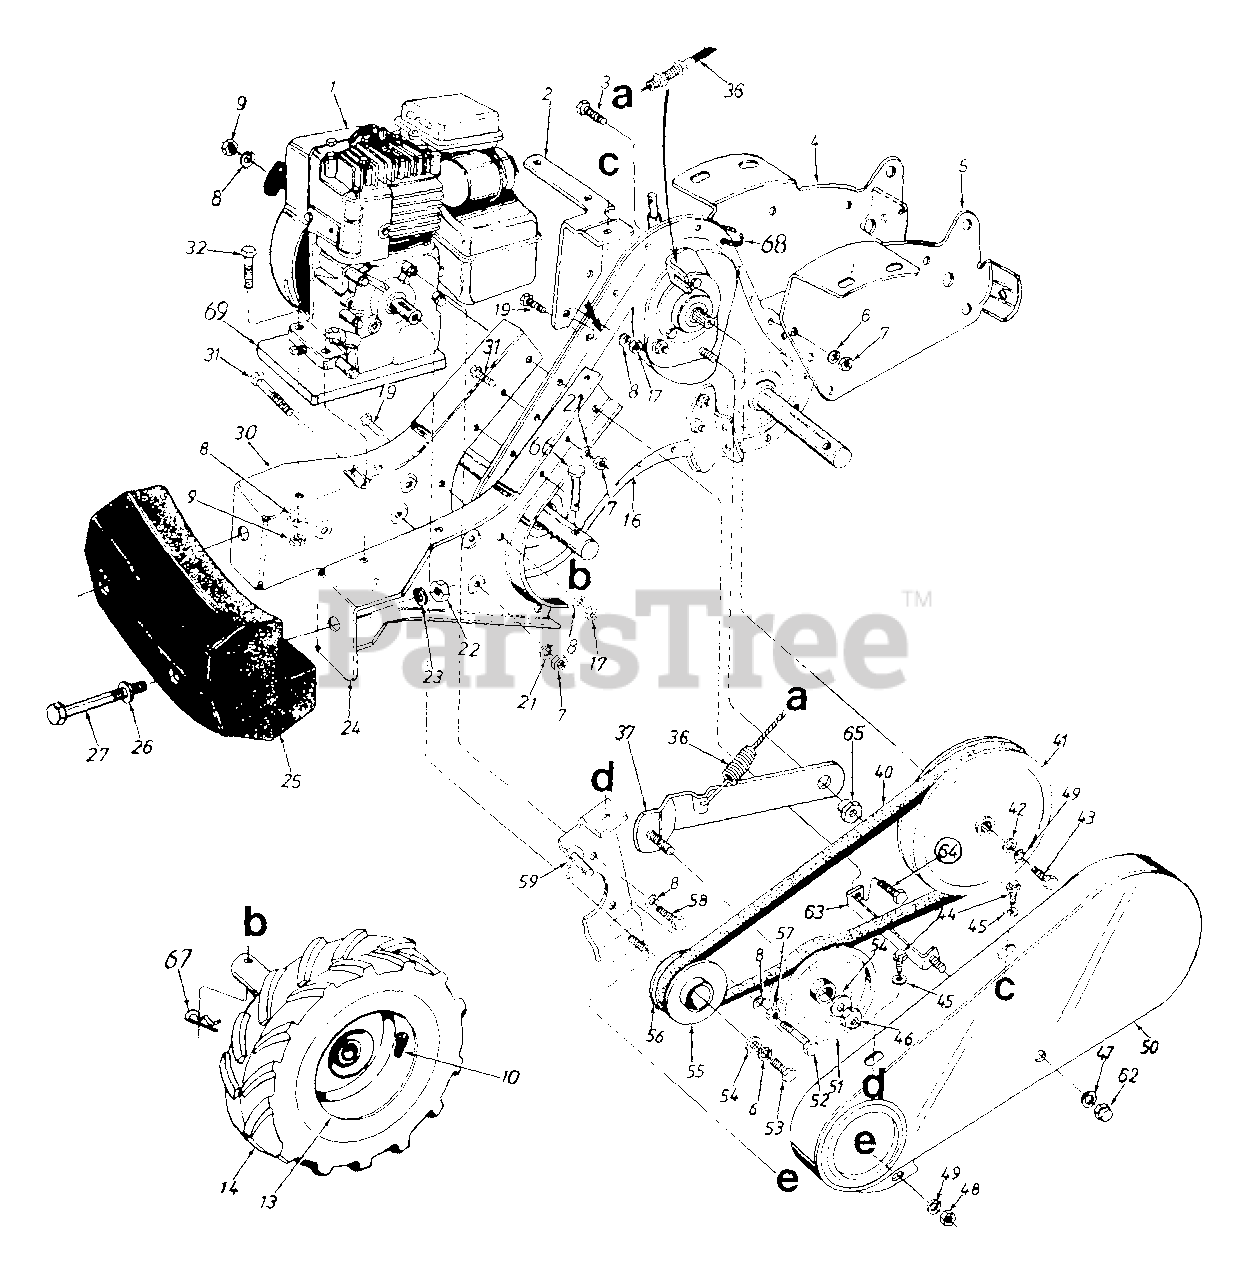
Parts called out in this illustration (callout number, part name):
1	Engine
7	Hex Nut 3/8-16 Thd.
8	L-Wash. 5/16" I.D.
9	Hex Nut 5/16-18" Thd.
10	Air Valve
16	Gear Case Ass'y. Comp.
17	Hex Nut 5/16-18 Thd.
19	Hex Bolt 5/16-18 x .75" Lg.
21	L-Wash. 3/8" I.D.- H.D.
22	Hex Nut 1/2-13 Thd.
23	L-Wash. 1/2" I.D.
26	FI-Wash..510" I.D. x 1.0"
27	Hex Bolt 1/2-13 x 5.00" Lg.
32	Hex Bolt 5/16-18 x 2.75"
36	Clutch Control Cable 46" Lg.
37	Idler Bracket Ass'y.
40	"V"-Belt
41	Fl-Pulley 8" O.D.
42	Fl-Wash. 1/4" I.D. x 93" 0 D.
43	Hex Bolt 1/4-28 x 75" Lg
44	Hex Wash Hd S-Tap Scr 1/4-20 x 50" Lg
45	FI-Wash..281" I.D. x 625"
46	Hex Cent. L-Nut 3/8-24 Thd.
47	Fl-Wash. 266" I D. x 625" O.D.
48	Hex Nut 1/4-20 Thd
49	L-Wash. 1/4" I.D.
51	Fl-Idler w/Flanges 3 75" 0 D.
52	Hex Bolt 5/16-24 x 1.75"
53	Hex Bolt 3/8-24 x 1.00" Lg.
54	Fl-Wash 3/8" I.D. x 1 00"
55	Outer Engine Pulley Half
56	Inner Engine Pulley Half
57	Hex Nut 5/16-24 Thd.
58	Hex Bolt 5/16-24 x .62" Lg.
59	Belt Keeper Ass'y
62	Hex Cap Nut 1/4-28 Thd.
63	Belt Cover Brkt. Ass'y
64	Hex Bolt 5/16-18 x 1" Lg. (Gr. 5)
65	Shld Nut
66	Clevis Pin
67	Hairpin Clip
68	Cable Tie - Self Clinching
69	Engine Spacer Block
